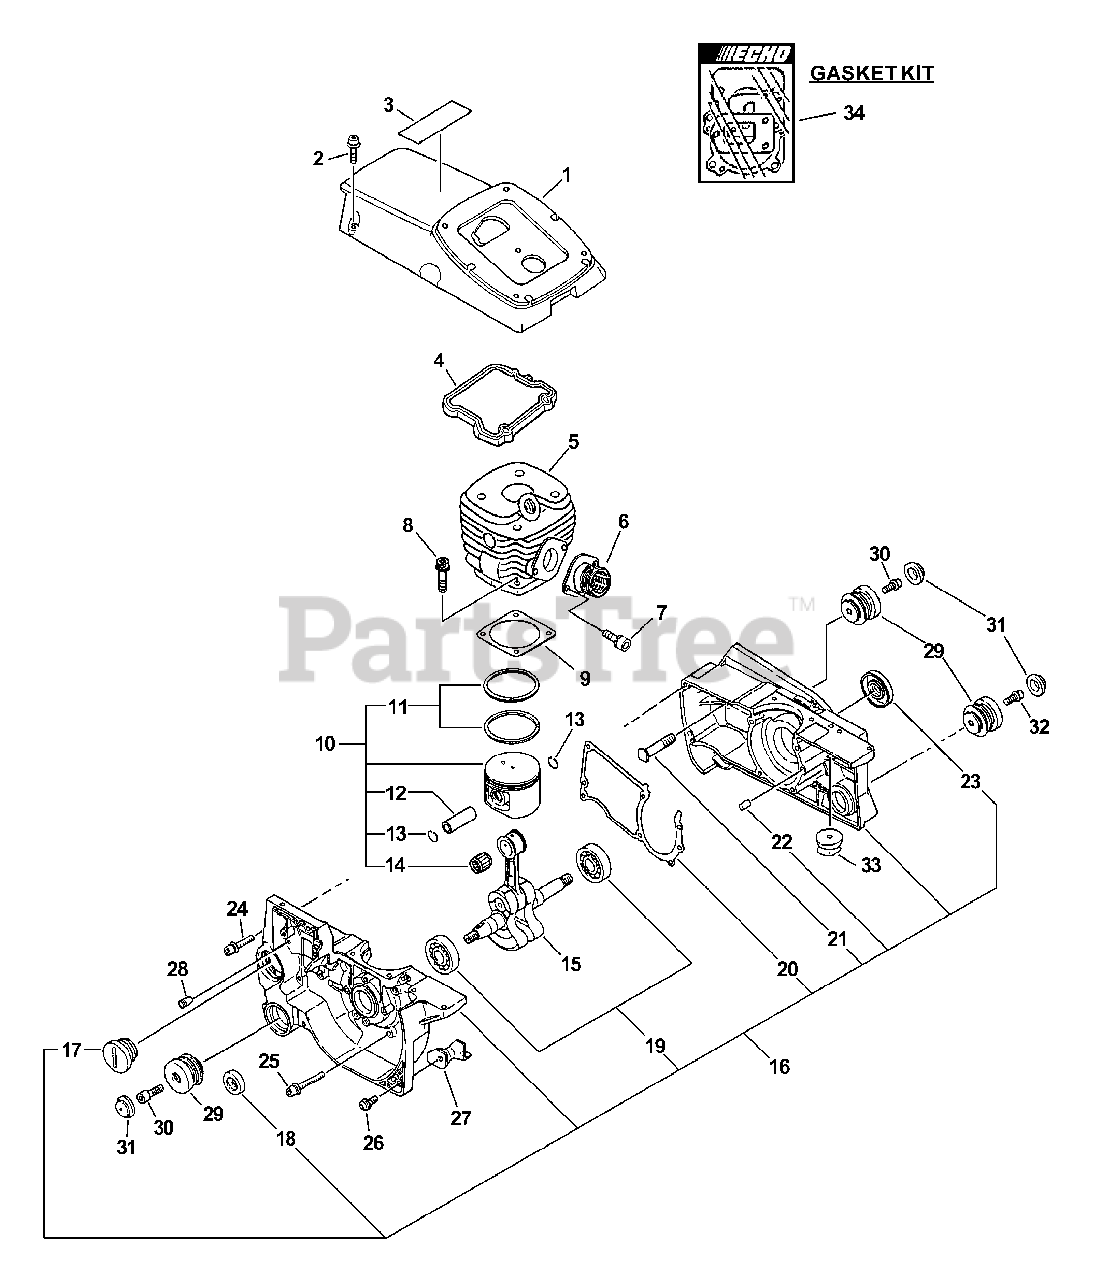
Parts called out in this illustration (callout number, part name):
1	COVER, ENGINE
2	SCREW - 5X20
3	LABEL - CAUTION
4	CUSHION
5	CYLINDER
6	BELLOWS, INTAKE
7	SCREW - 4X14
8	SCREW - 5X25
9	GASKET, CYLINDER
10	PISTON KIT
11	RING, PISTON
12	PIN, PISTON
13	RING, RETAINING
14	BEARING, NEEDLE
15	CRANKSHAFT ASSY
16	CRANKCASE KIT
17	CAP, OIL TANK
18	SEAL, OIL
19	BEARING, BALL - 6202
20	GASKET, CRANKCASE
21	STUD, GUIDE BAR
22	PIN - LOCATING
23	SEAL, OIL
24	SCREW - 5X20
25	SCREW - 5X35
26	SCREW - 5X14
28	VENT, TANK
31	CAP, CUSHION
32	SCREW - 5X14
33	CUSHION - A
34	GASKET KIT
